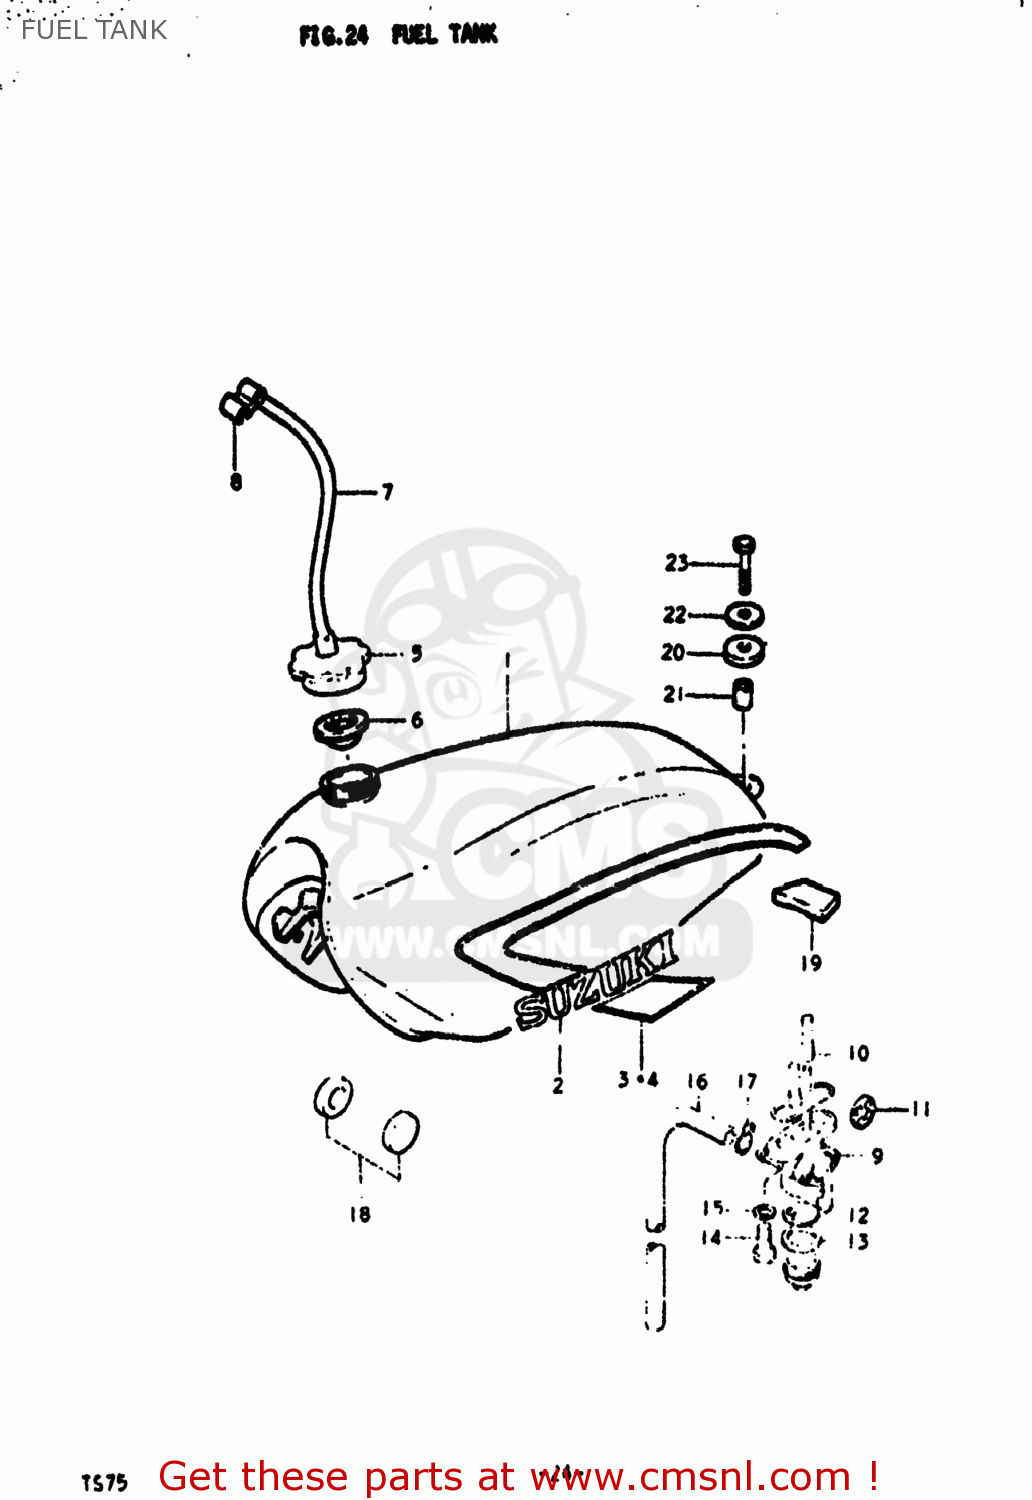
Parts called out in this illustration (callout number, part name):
1	TANK ASSEMBLY,FUEL
2	EMBLEM
3	TANK ASSEMBLY,FUEL
4	EMBLEM
